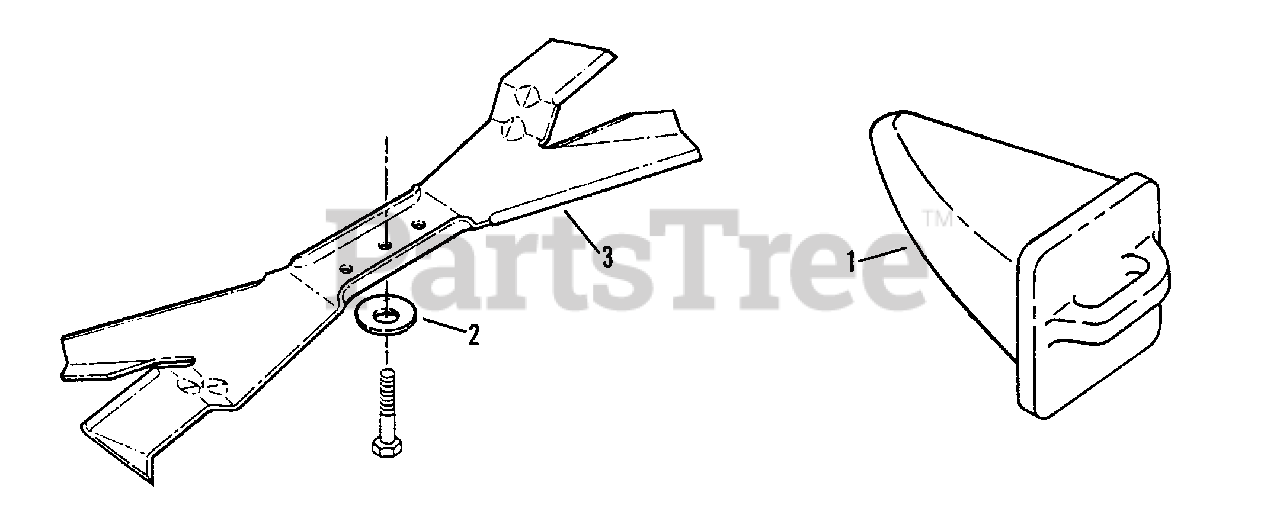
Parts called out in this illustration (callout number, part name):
1	PLUG, Mulching
2	WASHER, Cone
3	BLADE, 21" Ninja
